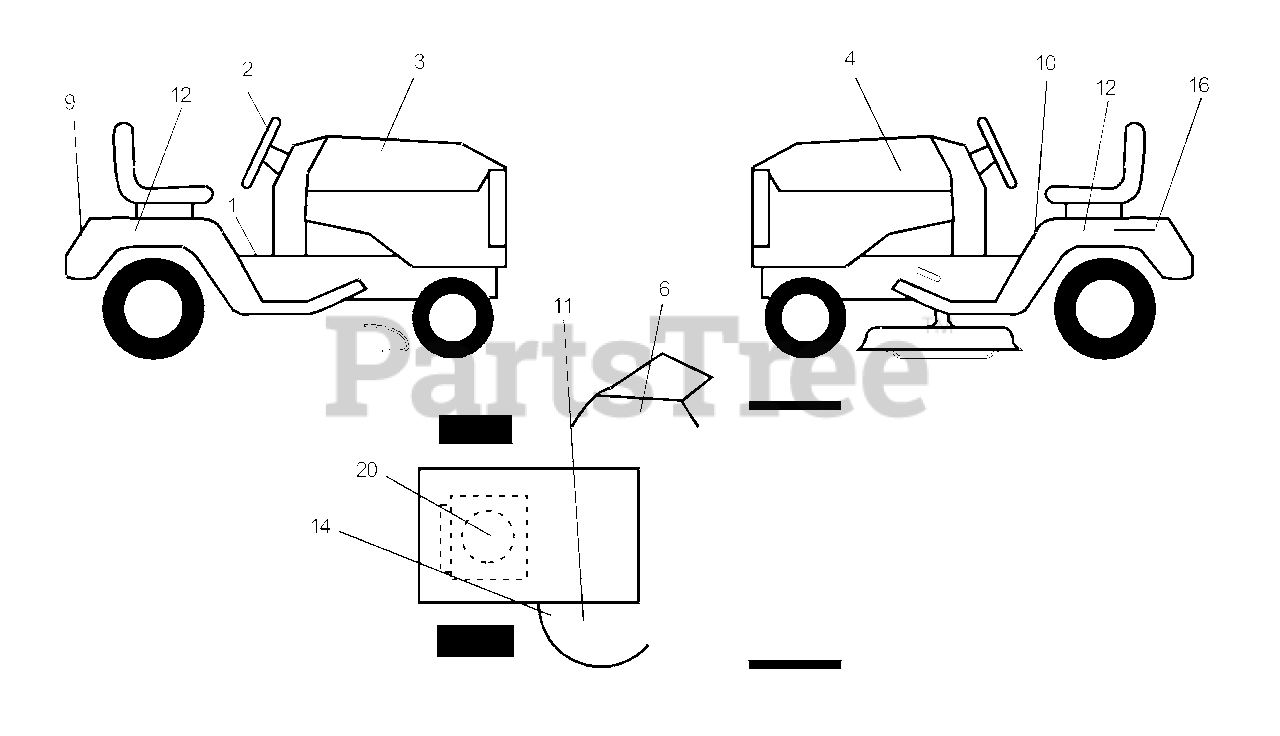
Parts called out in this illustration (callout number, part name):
1	Decal Instruction Operat English
2	Decal Ins Strg Wh
3	Decal Hood Rh
4	Decal Hood Lh
6	Decal, Warning
9	Decal Fender Logo
10	Decal Danger English
11	Decal Clutch/brake English
12	Decal Fender
14	Decal V-belt Schematic 42"
16	Decal Battery Danger/Poison
20	Decal HP Engine
